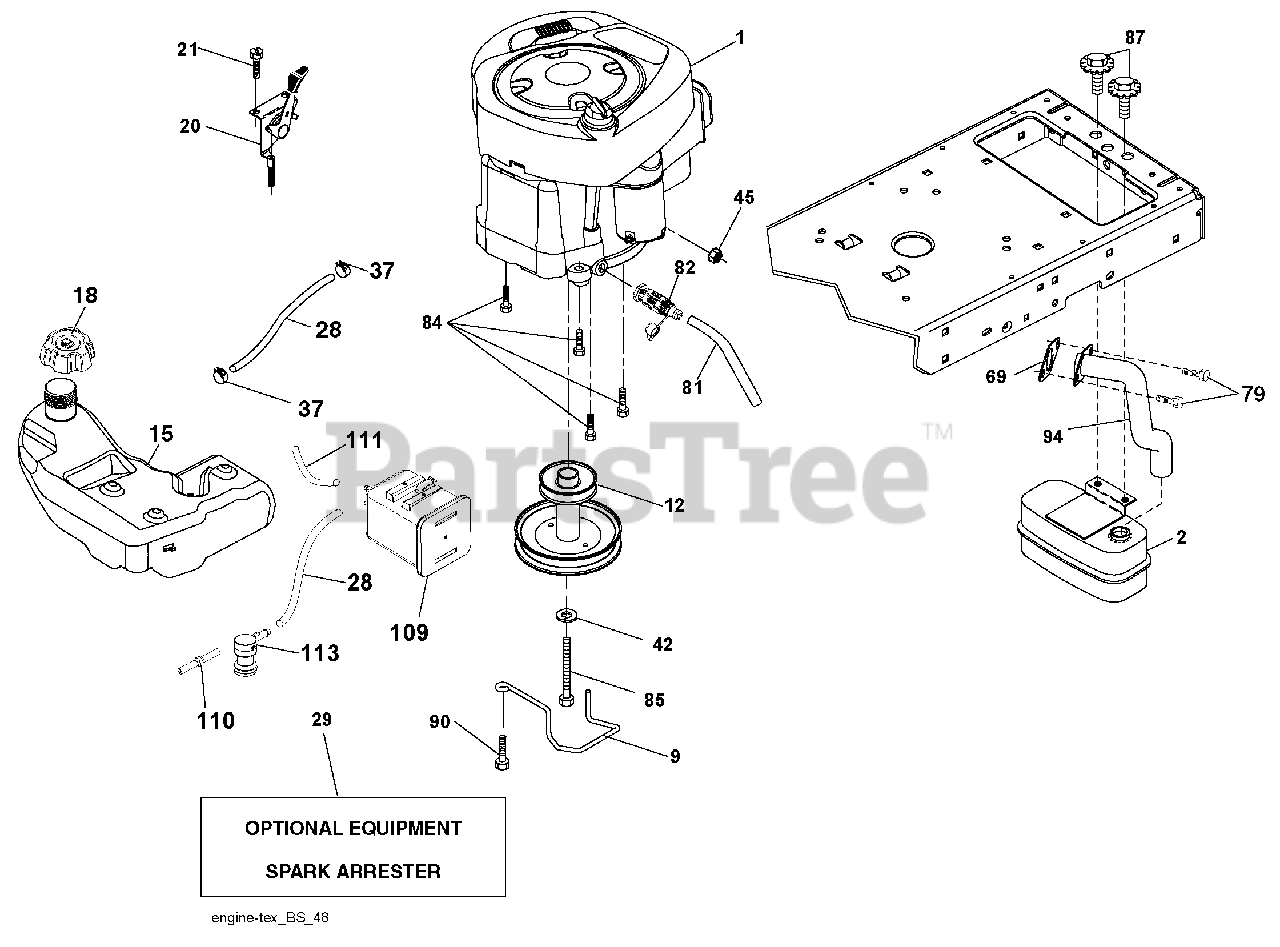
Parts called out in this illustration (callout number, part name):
9	Keeper Belt Engine
12	Pulley Engine
15	Tank Fuel
18	Cap Asm
20	Control Throttle/Choke
21	Screw #10 X 0.750 Bos Thread
28	Fuel Line
29	Spark Arrester Kit
37	Clamp Hose
42	Washer Lock 7/16
45	Nut Keps Hex 1/4-20 Unc
69	Gasket
79	Screw 5/16-18 X 3/4
81	Tube Drain Oil Easy
82	Valve Drain Oil
84	Screw 3/8-16 X 1/4
85	Bolt Hex 7/16-20 X 4 Gr. 5
87	Bolt 5/16-18 Unc X 3/4 W/Sems
90	Screw 3/8-16 X 1
94	Exhaust Tube
109	Canister Carbon Filter Asm
110	Valve Anti Slosh
111	Purge Line
113	Valve Slant Cartrdg
